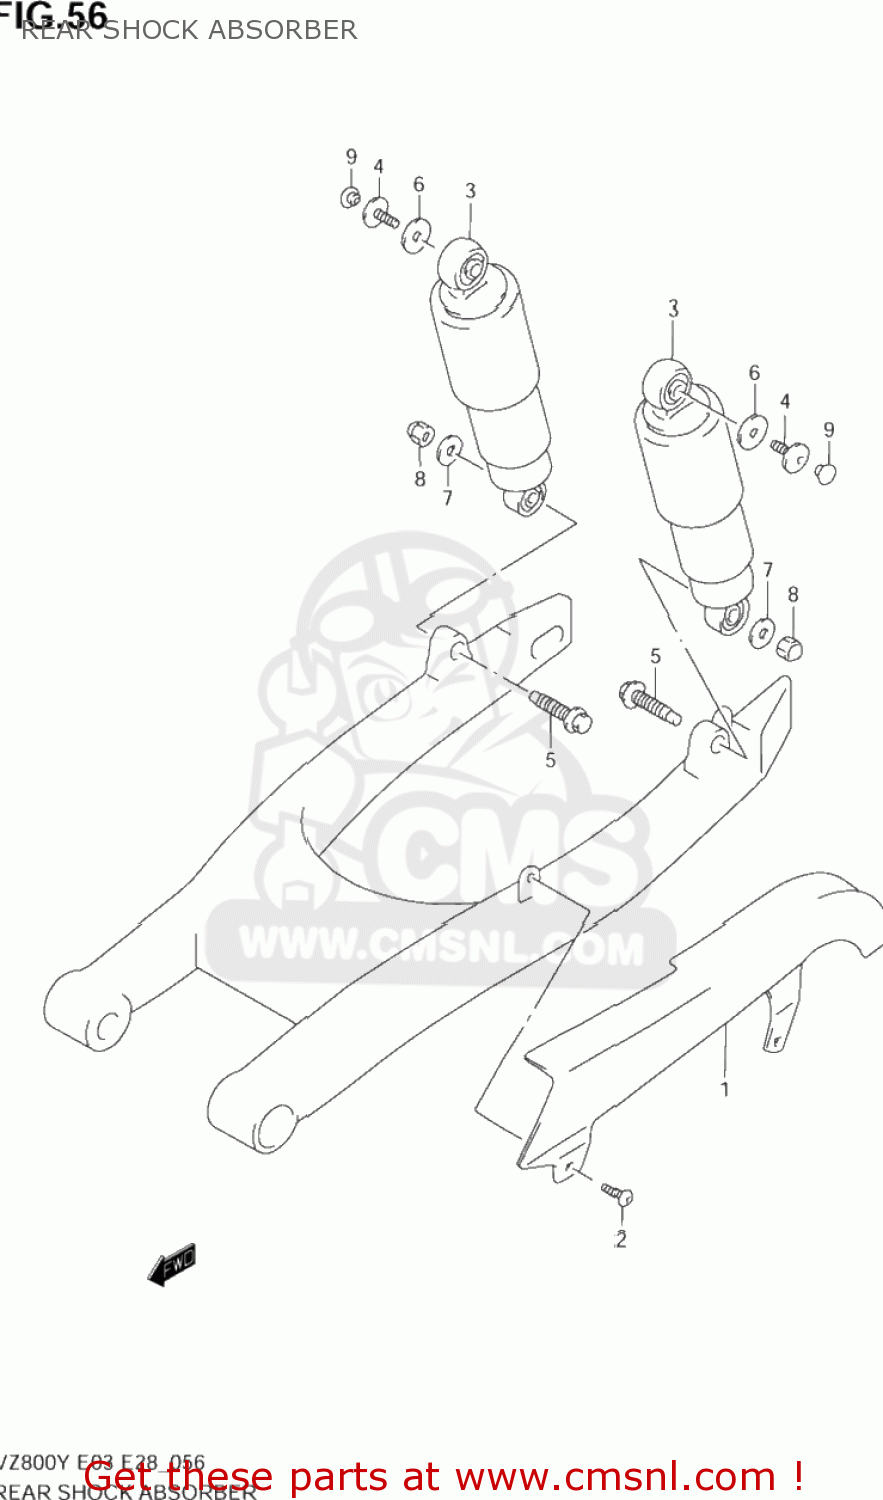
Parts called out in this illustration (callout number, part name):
1	CASE,CHAIN
2	SCREW
3	ABSORBER ASSY,RR SHOCK
4	BOLT(8X20)
5	BOLT,RR SHOCK ABSORBER
6	WASHER (8.5X30X2.3)
7	WASHER(10.5X28X2.3)
8	NUT
9	CAP(OD:14.5)
